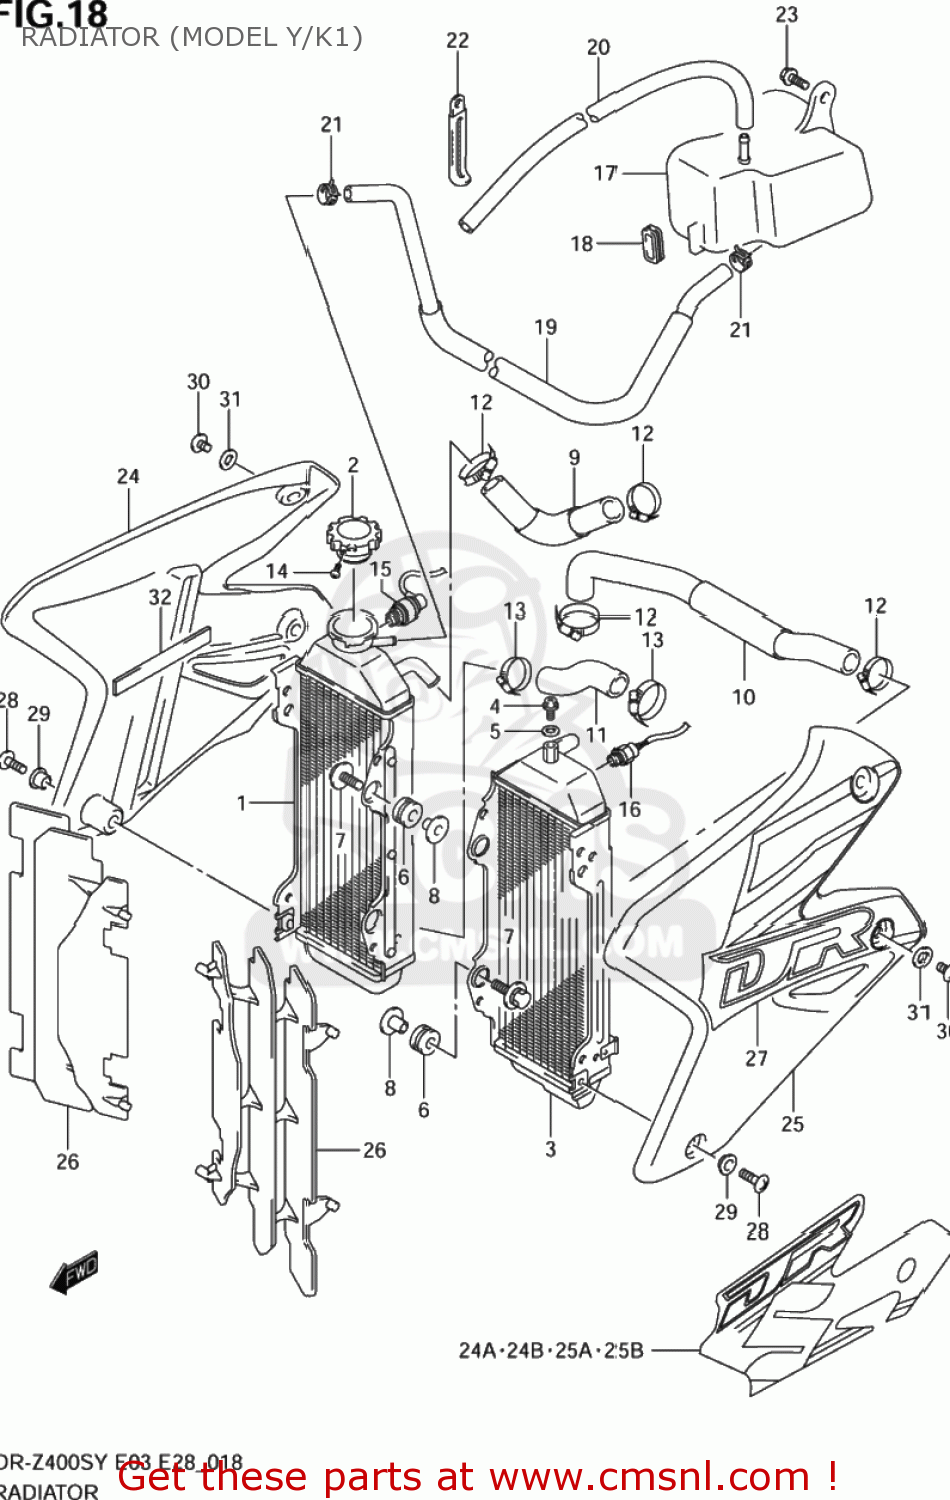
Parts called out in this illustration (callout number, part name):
1	RADIATOR COMP,WATER,RIGHT
2	CAP,RADIATOR(1.1)
3	RADIATOR COMP,WATER,LEFT
4	UNION BOLT,AIR VENT
5	GASKET(6.4X11.5X0.8) (NAS)
6	CUSHION,RADIATOR LWR
7	BOLT(6X25)
8	SPACER(6.5X10.5X14.1)
9	HOSE,RADIATOR JOINT
10	HOSE,RADIATOR OUTLET
11	HOSE,RADIATOR INLET
12	CLAMP
13	CLAMP
14	SCREW,RADIATOR CAP
15	SWITCH ASSY,WATER TEMP
16	SWITCH,FAN
17	TANK,RESERVOIR
18	CUSHION,RESERVOIR TANK
19	HOSE,RESERVOIR TANK INLET
20	HOSE(5X9X2000)
21	CLIP
22	CLAMP(L:65)
23	BOLT
24	COVER,RADIATOR
24A	TAPE,RADIATOR COVER,R
24B	TAPE,RADIATOR COVER,R
25	COVER,RADIATOR
25A	TAPE,RADIATOR COVER,L
25B	TAPE,RADIATOR COVER,R
26	LOUVER,RADIATOR
27	TAPE,RADIATOR COVER,R
28	SCREW
29	WASHER
30	SCREW
31	WASHER
32	CUSHION,COVER SIDE
